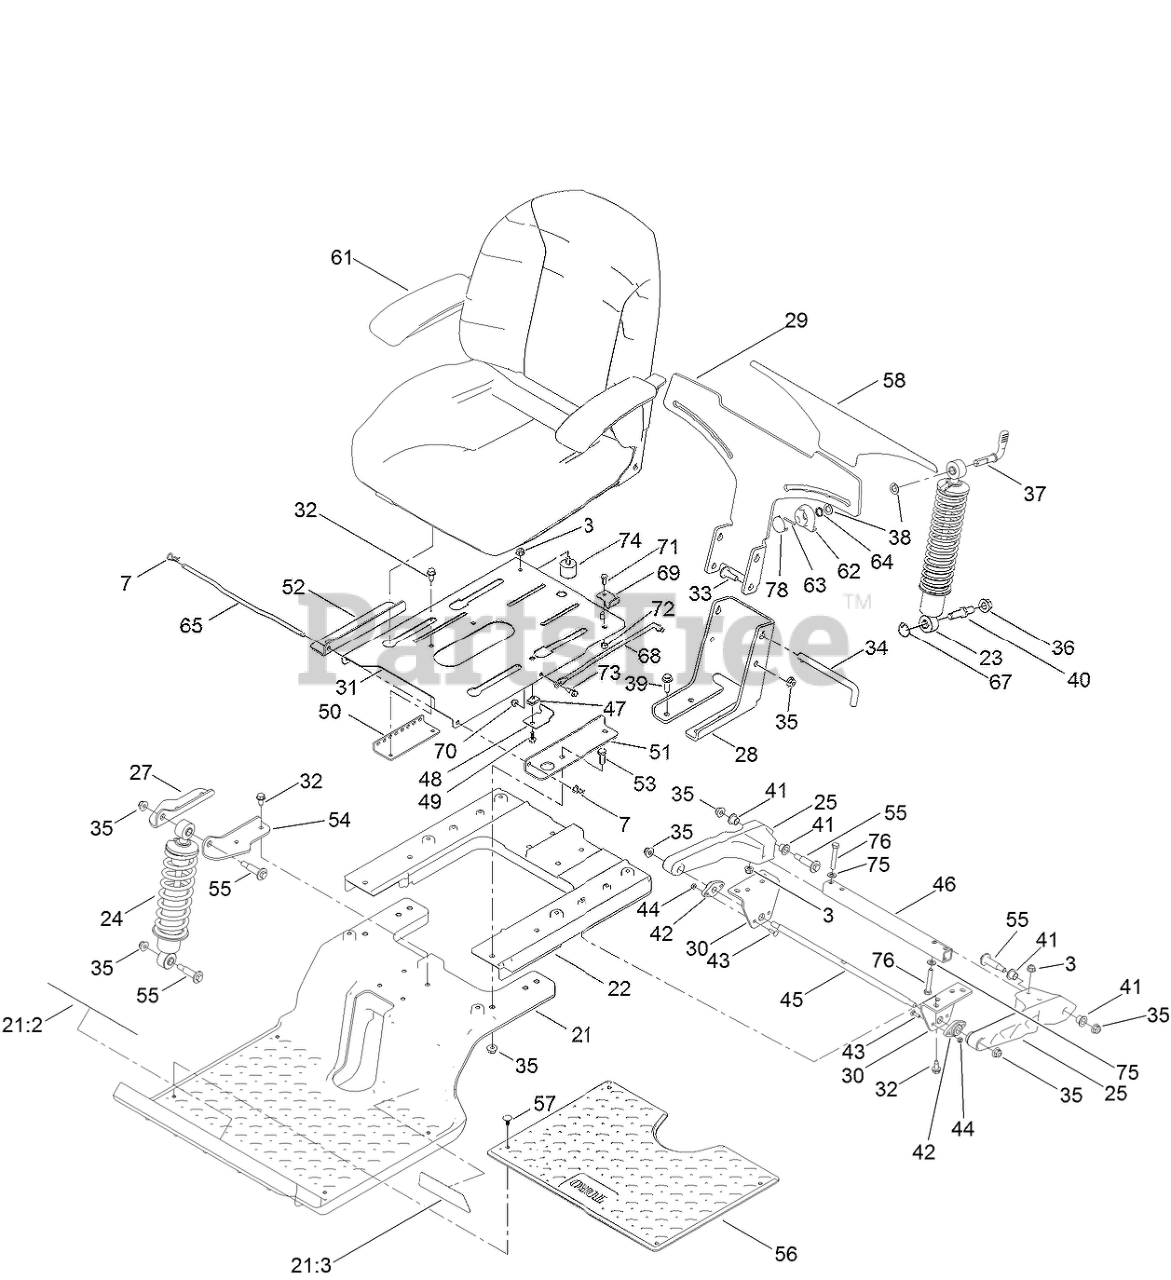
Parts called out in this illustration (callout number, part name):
3	NUT-HF, NI
7	PIN-COTTER
21	SUBFRAME-FRONT
21:2	DECAL-DANGER
22	SUBFRAME-REAR
23	SHOCK/SPRING ASM
24	SHOCK ASM
25	TRAILING ARM
27	BRACKET-SHOCK MOUNT, UPPER (RH)
28	BRACKET-MOUNT, LOWER
29	PLATE-MOUNTING, SHOCK
30	BRACKET-MOUNT, SWING ARM
31	PAN-SEAT
32	SCREW-HWHTF
33	SCREW-SHOULDER, HHF
34	PIN-HOC
35	NUT-HF, NI
36	NUT-LOCK
37	HANDLE-ADJUSTMENT
38	WASHER-THRUST
39	SCREW-THD
40	BOLT-SHOULDER
41	BUSHING-FLANGE
42	BEARING-FLANGE
43	SCREW-CARR
44	NUT-LOCK, NI
45	ROD-PIVOT
46	TUBE-ARM, TRAILING
48	BRACKET-STOP, SEAT
49	SCREW-HHF
50	BRACKET-LATCH, SEAT
51	BRACKET-SEAT, RH
52	BRACKET-SEAT, LH
53	SCREW-HH
54	BRACKET-SHOCK MOUNT, UPPER (LH)
55	BOLT-SHOULDER
56	FLOORMAT
57	PLUG-PLASTIC
58	DECAL-ADJUSTMENT
61	SEAT ASM - TORO
62	LOCK-CAM
63	PIN-LOCK, CAM
64	SPRING-WAVE
65	ROD-STOP
67	PIN-COTTER, CIRCULAR
68	BRACE-SEAT
69	BRACKET-BRACE, SEAT
70	NUT-HF
71	SCREW-HH
72	NUT-LOCK, NI
73	BOLT-SHOULDER
74	BUMPER-RUBBER
75	WASHER-PLAIN
76	SCREW-HH
78	CAP-LOCK, CAM
